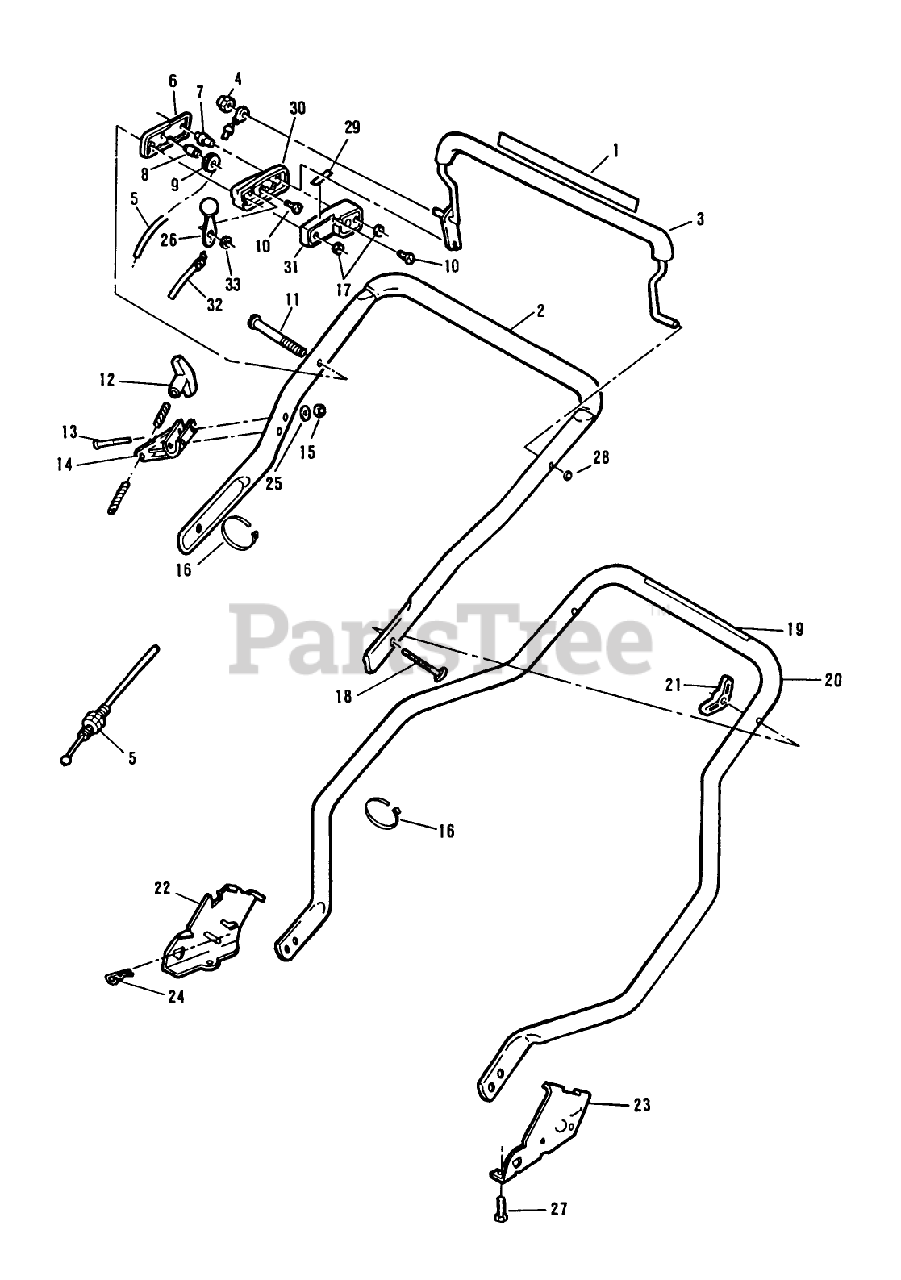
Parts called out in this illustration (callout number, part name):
2	HANDLE SECTION
3	CONTROL LEVER ARG
4	NUT ACORN
5	CONTROL CABLE WES
6	OUTER CONTROL CASE
7	COLUMN
8	PIN SKF
9	PULLEY PL
10	SCREW
11	SCREW
12	HANDLE START UM&D
15	LOCKNUT E
17	NUT C/LOCK E
18	BOLT QUALITY
21	NUT-WING
24	HAIR PIN
25	WASHER
26	LEVER&KNOB AY WES
27	SCREW
32	CABLE THROT WES
33	WASHER-SPRING
